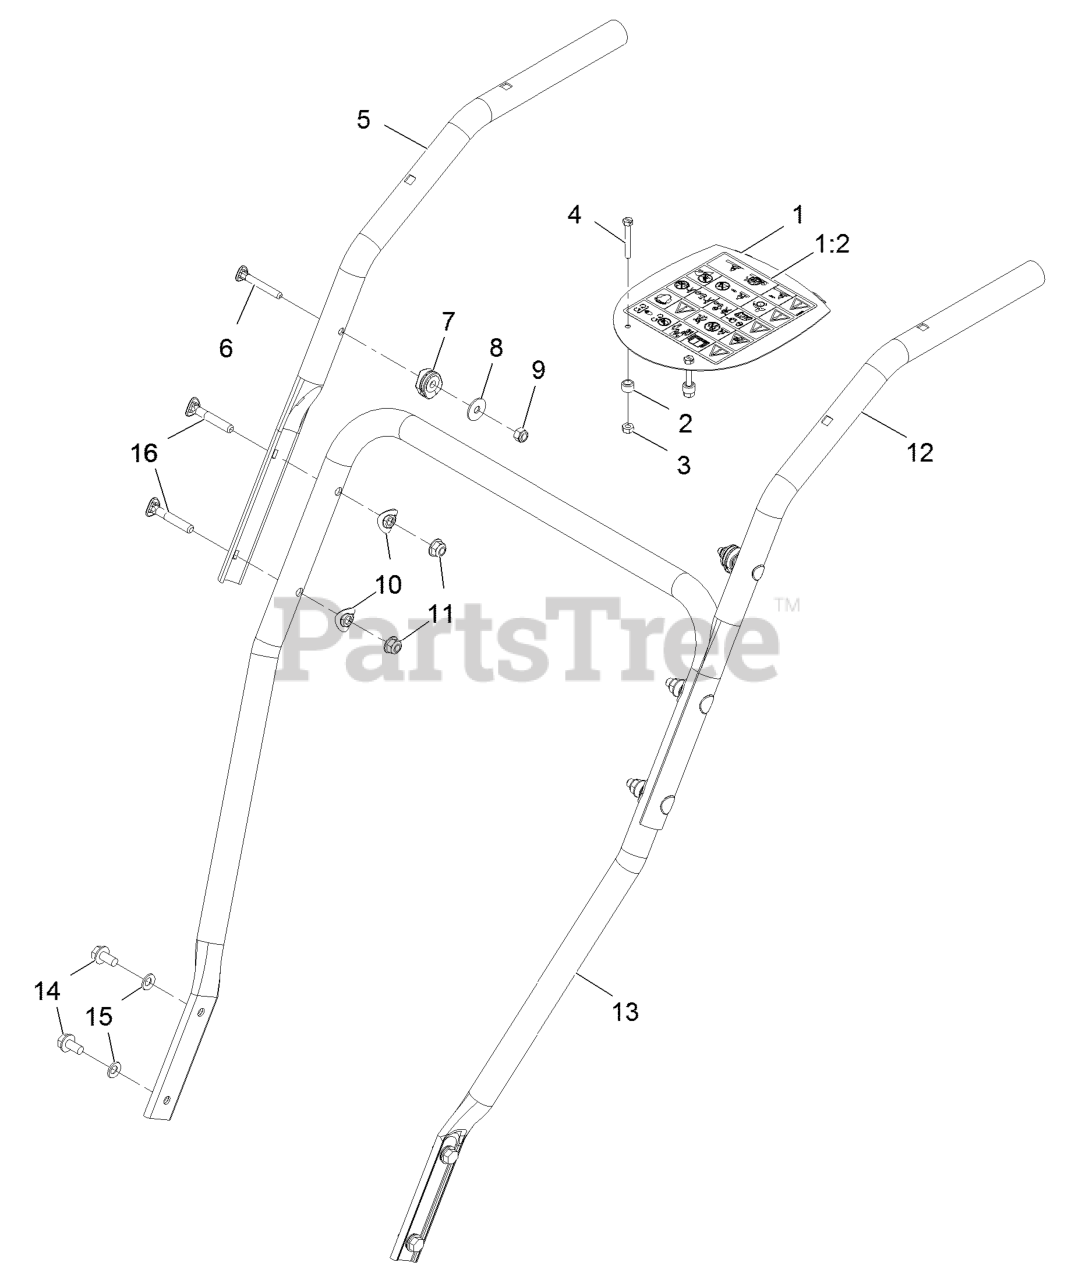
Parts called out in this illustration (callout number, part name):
1	PANEL-CONTROL
1:2	DECAL-WARNING
2	SPACER-BLADE, ROTOR
3	NUT-LOCK, NI
5	HANDLE-UPPER, RH
7	CLAMP-CABLE
8	WASHER-PLAIN
9	NUT-LOCK, NI
11	NUT-HF, NI
13	HANDLE-LOWER
14	SCREW-HWHTF
15	WASHER-BELLEVILLE
16	SCREW-HANDLE
